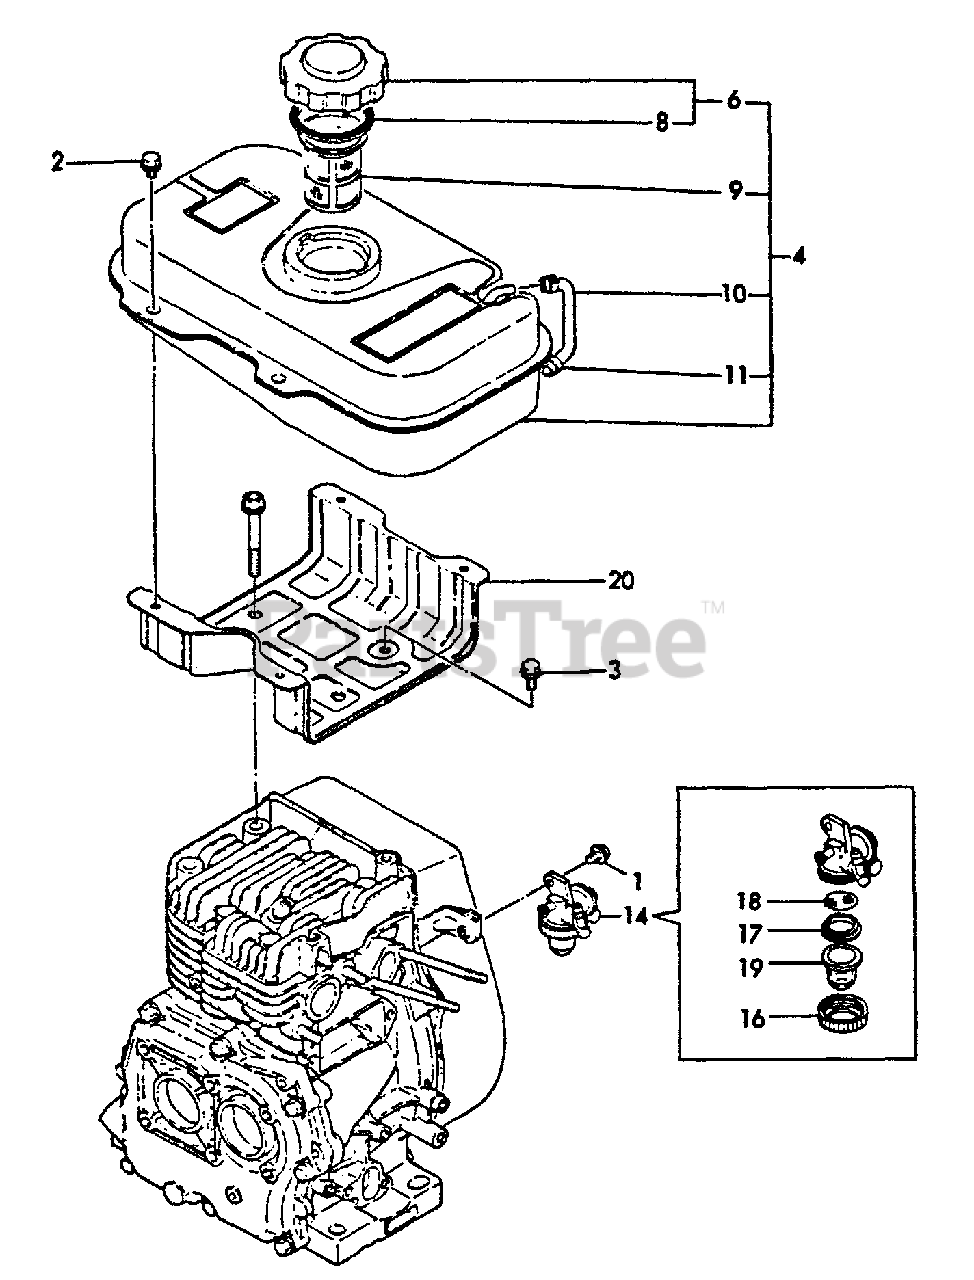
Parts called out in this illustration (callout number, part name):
1	BOLT - 6×8 -- PLATED
2	BOLT - 6×10 -- PLATED
3	BOLT - 6×8 -- PLATED
4	FUEL TANK ASSY
6	CAP ASSY
8	GASKET
9	STRAINER, FUEL
10	PIPE, GAUGE
11	CLAMP, HOSE - 9
14	COCK ASSY, FUEL
16	RETAINER
17	GASKET
18	FILTER, FUEL
19	BOWL, STRAINER
20	BRACKET, FUEL TANK
